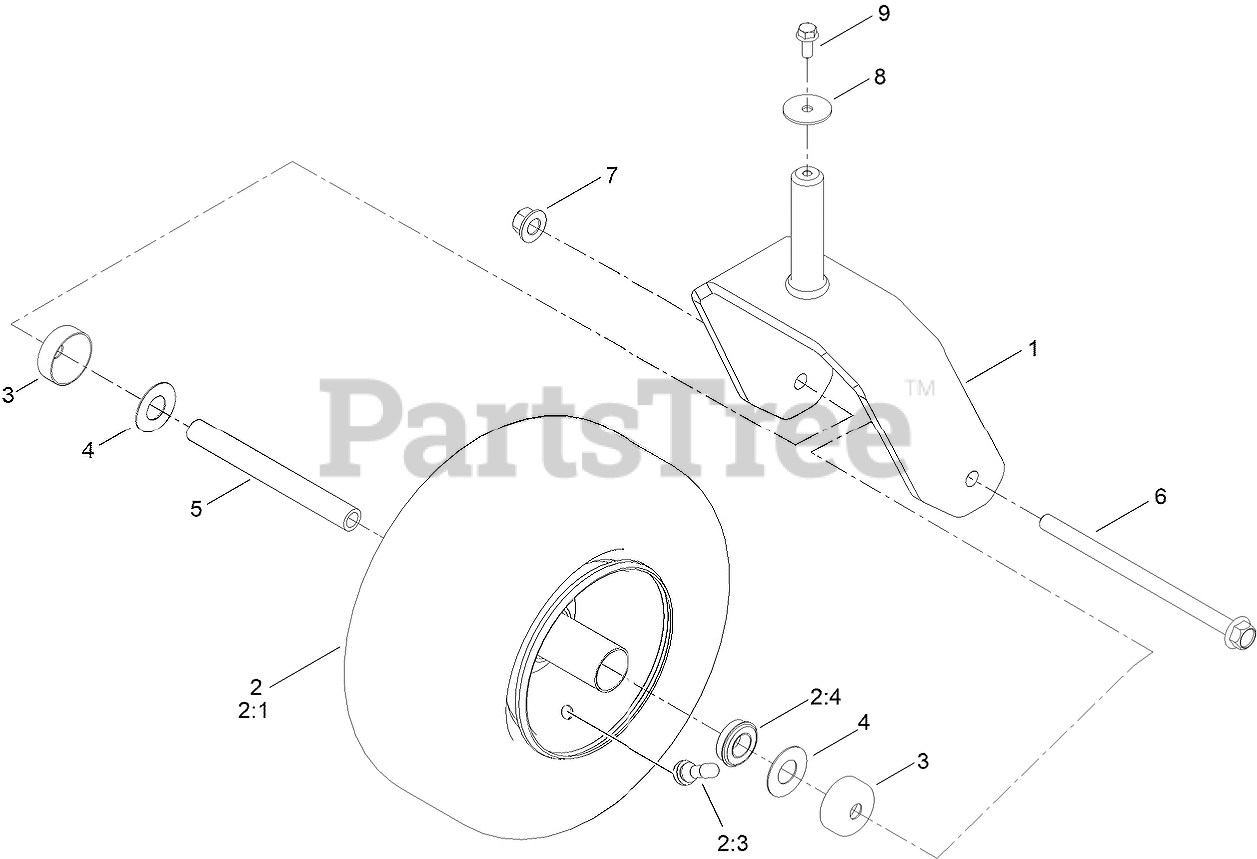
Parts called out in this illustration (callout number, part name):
1	FORK ASM [BLK-TXT]
2	TIRE ASM
2:4	BEARING
3	GUARD-SEAL
4	WASHER
5	SPANNER-WHEEL
6	SCREW-HHF
7	NUT-LOCK
8	WASHER-FLAT
9	SCREW-HHF
